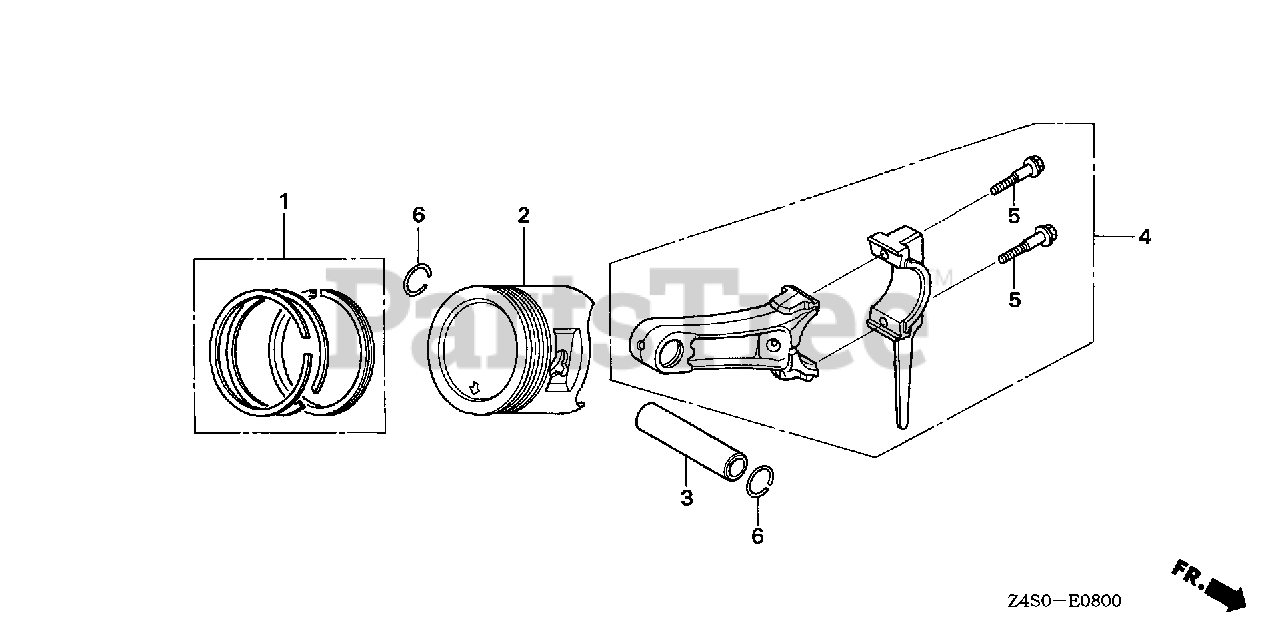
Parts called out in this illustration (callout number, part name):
1	RING SET, PISTON (STD) (TEIKOKU)
1	RING SET, PISTON (STD.) (NIPPON)
1	RING SET, PISTON (STD) (TPR)
1	RING SET, PISTON (0.25) (TEIKOKU)
1	RING SET, PISTON (0.25) (NIPPON)
1	RING SET, PISTON (0.25) (TPR)
1	RING SET, PISTON (0.50) (TEIKOKU)
1	RING SET, PISTON (0.50) (NIPPON)
1	RING SET, PISTON (0.50) (TPR)
1	RING SET, PISTON (0.75) (TEIKOKU)
1	RING SET, PISTON (0.75) (NIPPON)
1	RING SET, PISTON (0.75) (TPR)
2	PISTON (STD)
2	PISTON (0.25)
2	PISTON (0.50)
2	PISTON (0.75)
3	PIN, PISTON
4	ROD ASSY., CONNECTING (STD)
4	ROD ASSY., CONNECTING (TH)
5	BOLT, CONNECTING ROD
6	CLIP, PISTON PIN (18MM)
